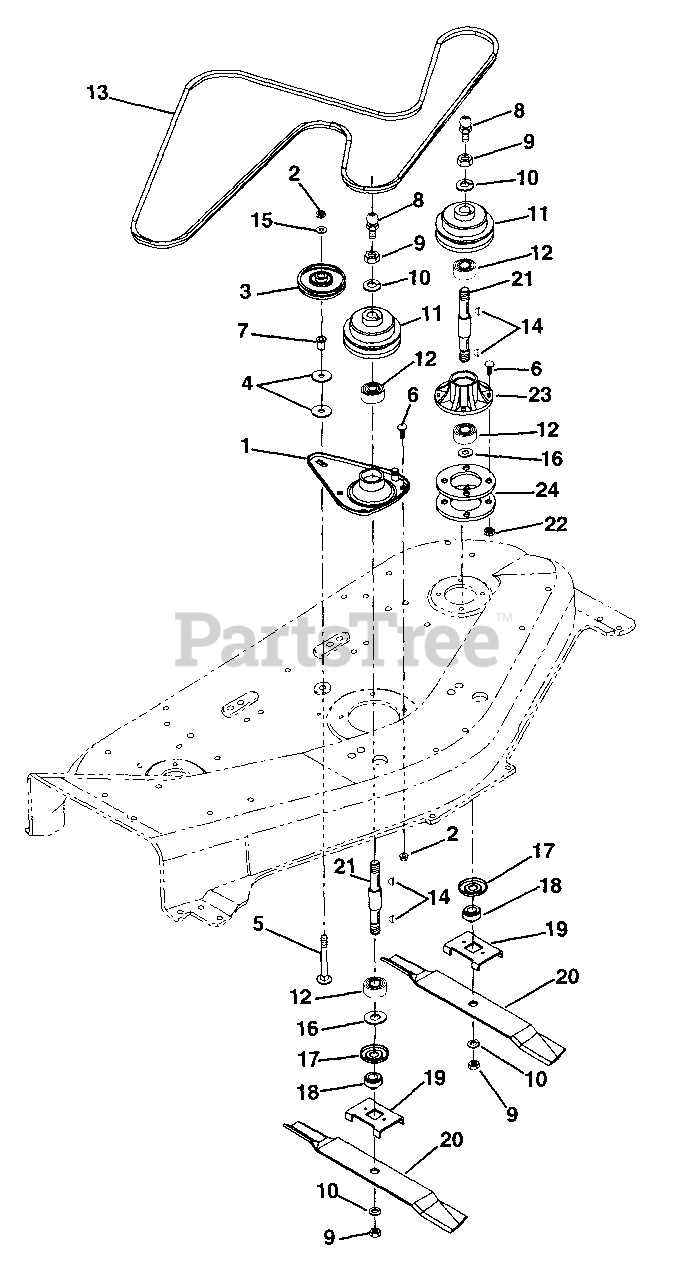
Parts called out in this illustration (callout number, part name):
1	Housing Spindle
2	Nut-Locking-Center .38-16
3	Idler-Plastic 4.75 OD x .50 ID
4	Washer-Flat-Steel .390 x 1.50 x .125
5	Bolt-Round Head Square Neck .38-16 x 2.00
6	Bolt-Round Head Square Neck .38-16 x .75 Grade 5
7	Spacer-Flanged .390 x .500 x .781 x .875
8	Fitting-Lube .25-28 x .256
9	Nut-Jam .75-10
10	Washer-Locking .75 x .188
12	Bearing-Ball .750 x 1.781 x .61
13	V-Belt 48" Pan
14	Key-Woodruff .188 x .62 x .25
15	Washer-Flat-Steel .38 x .875 x .083
16	Washer-Flat-Steel .754 x 1.000 x .032
17	Bearing Slinger
18	Retainer Hub
19	Blade Tray 48
20	Blade
21	Spindle Shaft w/Zerk
22	Nut-Jam-Locking .38-16
23	Spindle Housing
24	Spacer-Spindle
